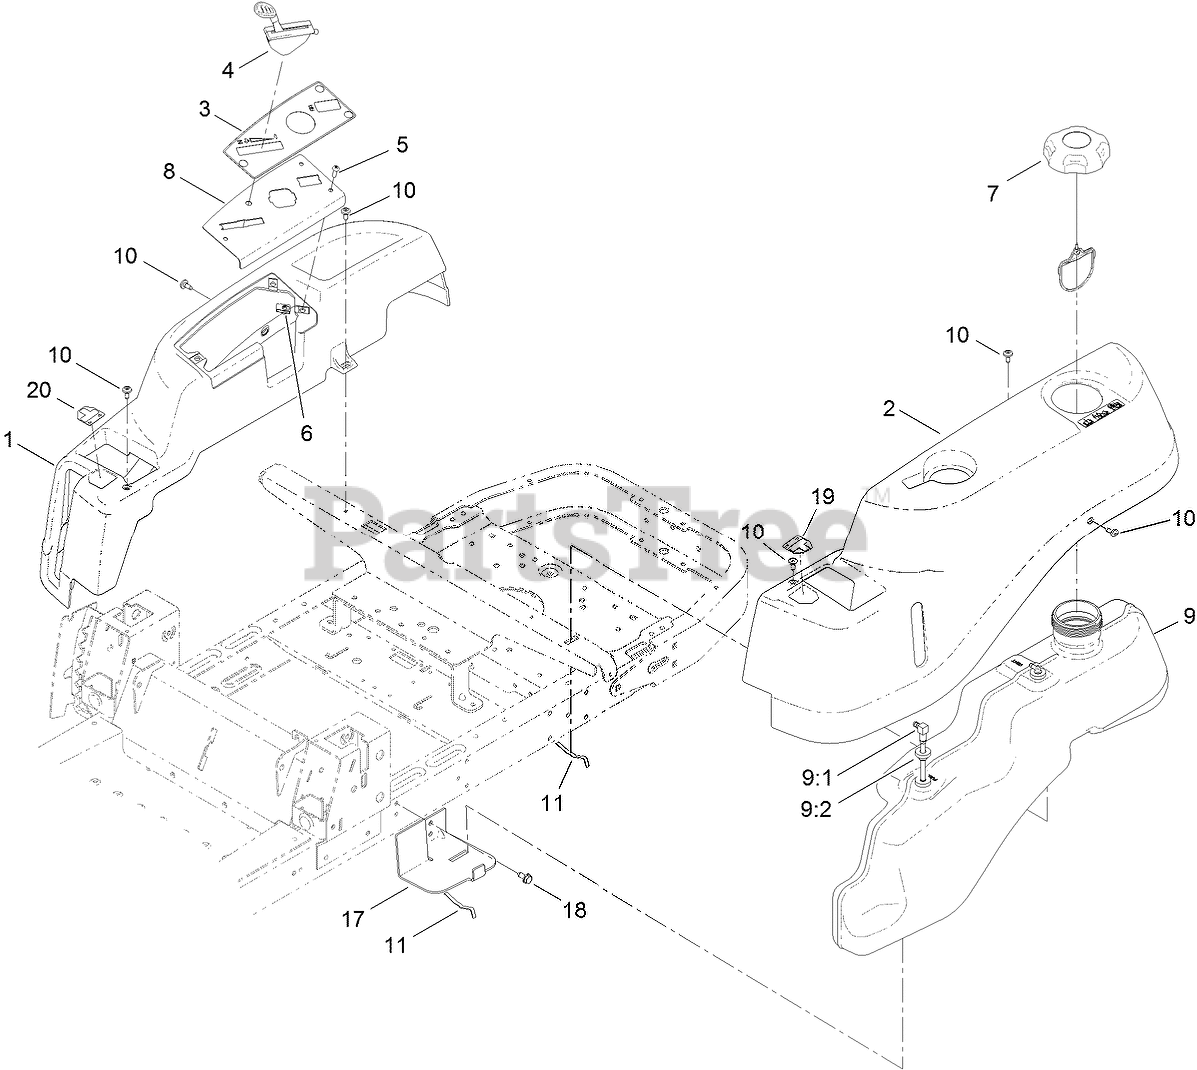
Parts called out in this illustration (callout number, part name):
1	POD-RH
2	POD-LH
3	DECAL-PANEL, CONTROL
4	CABLE-THROTTLE AND CHOKE
5	SCREW-PRH
7	CAP-FUEL, RATCHETING
8	PLATE-CONTROL
9	FUEL TANK ASM
9:1	CONNECTOR-ELBOW, 90 DEG
9:2	BUSHING
10	SCREW-SHOULDER
11	SPRING
17	SUPPORT-TANK, FRONT
18	SCREW-HWHTF
19	DECAL-CONTROL LEVER, LH
20	DECAL-CONTROL LEVER, RH
